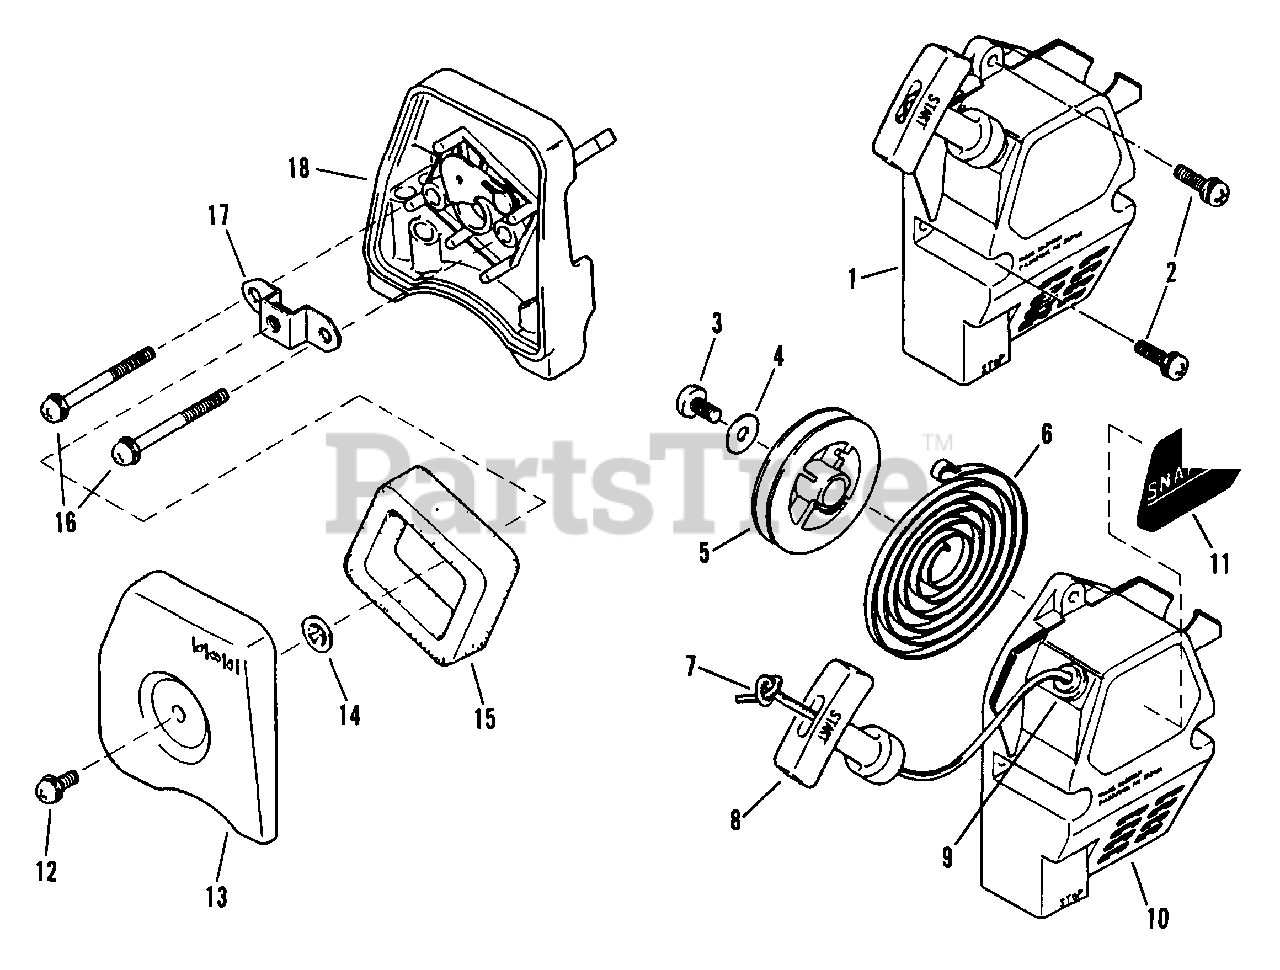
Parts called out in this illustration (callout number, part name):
1	ASSEMBLY, Recoil Starter
2	SCREW/WASHER
7	ROPE, Starter
8	KNOB, Starter
10	CASE, Starter
11	LABEL, Snapper
12	SCREW/WASHER
13	COVER, Cleaner
15	ELEMENT, Cleaner
16	SCREW/WASHER
17	BRACKET
18	CASE, Cleaner
